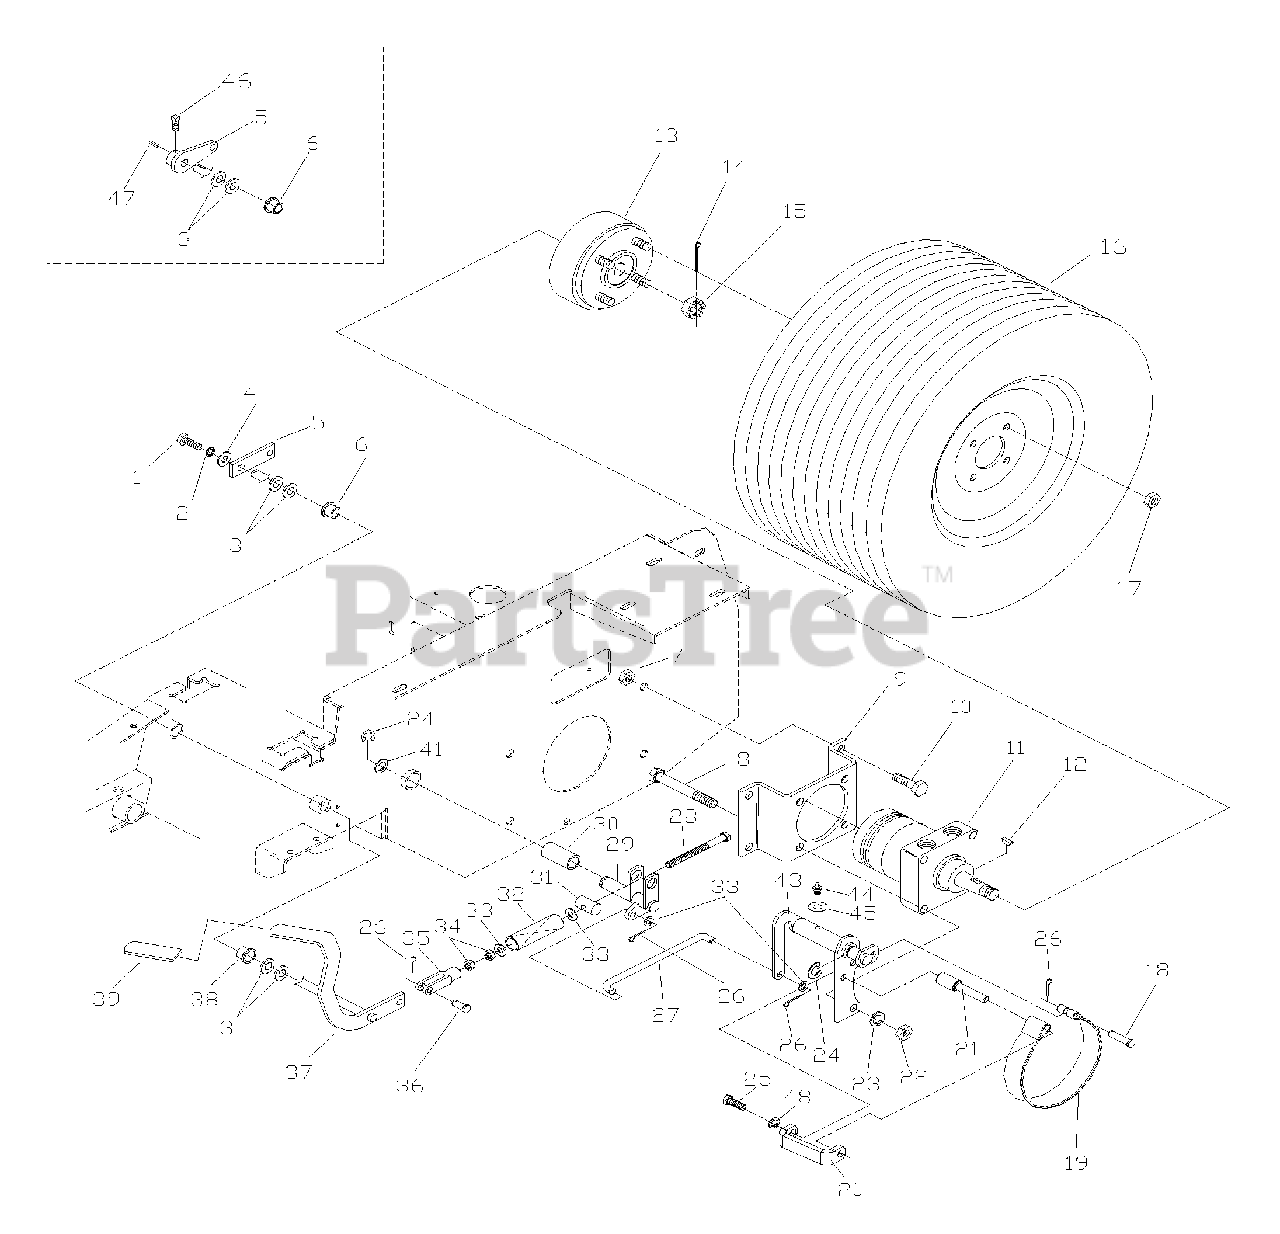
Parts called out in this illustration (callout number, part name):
1	HCS 1/4C X 3/4
2	1/4 LOCK WASHER
3	WASHER 7/16 SPRING
4	1/4 FLAT WASHER
5	ARM, PARK BRAKE
5	ARM, PARK BRAKE (NEW STYLE)
7	NUT 1/2C NYLOC
8	HCS 1/2C X 2.75
9	MOTOR STANDOFF
10	HCS 1/2C X 1.25
11	WHEEL MOTOR
12	WOODRUFF KEY
13	HUB W/ BRAKE DRUM
14	COTTER PIN
15	CASTLE NUT
16	REAR TIRE ASM OFFSET RIM (61" & 72" MODELS)
16	REAR TIRE ASM
16	RIM (OFFSET)
17	LUG NUT 1/2F
18	3/8 X 1.50 CLEVIS PIN
19	BRAKE BAND
20	SUPPORT BKT. - AFTER 03/2002
20	HCS 3/8C X 3 GD 8
21	BAND PIVOT - AFTER 03/2002
23	1/2 LOCK WASHER
24	E - RING 3/4
25	HCS 3/8 X 1.0 GD 8 - AFTER 03/2002
25	NUT 3/8C CTR. LOCK
26	COTTER PIN
27	BRAKE LINKAGE LT.
27	BRAKE LINKAGE RT.
28	HCS 3/8F SPECIAL
30	BRONZE BEARING
31	TRUNION PIN
33	3/8 SAE WASHER
36	3/8 X 1.125
37	BRAKE LEVER WLDMT.
37	BRAKEARM WLDMT (NEW STYLE)
41	MACH. BUSHING 3/4
43	LEFT BRAKE BKT.
43	RIGHT BRAKE BKT.
44	ZERK
46	SETSCRW. 5/16 X .625
47	KEY 1/4 X .875
48	WASHER 3/8 LOCK
